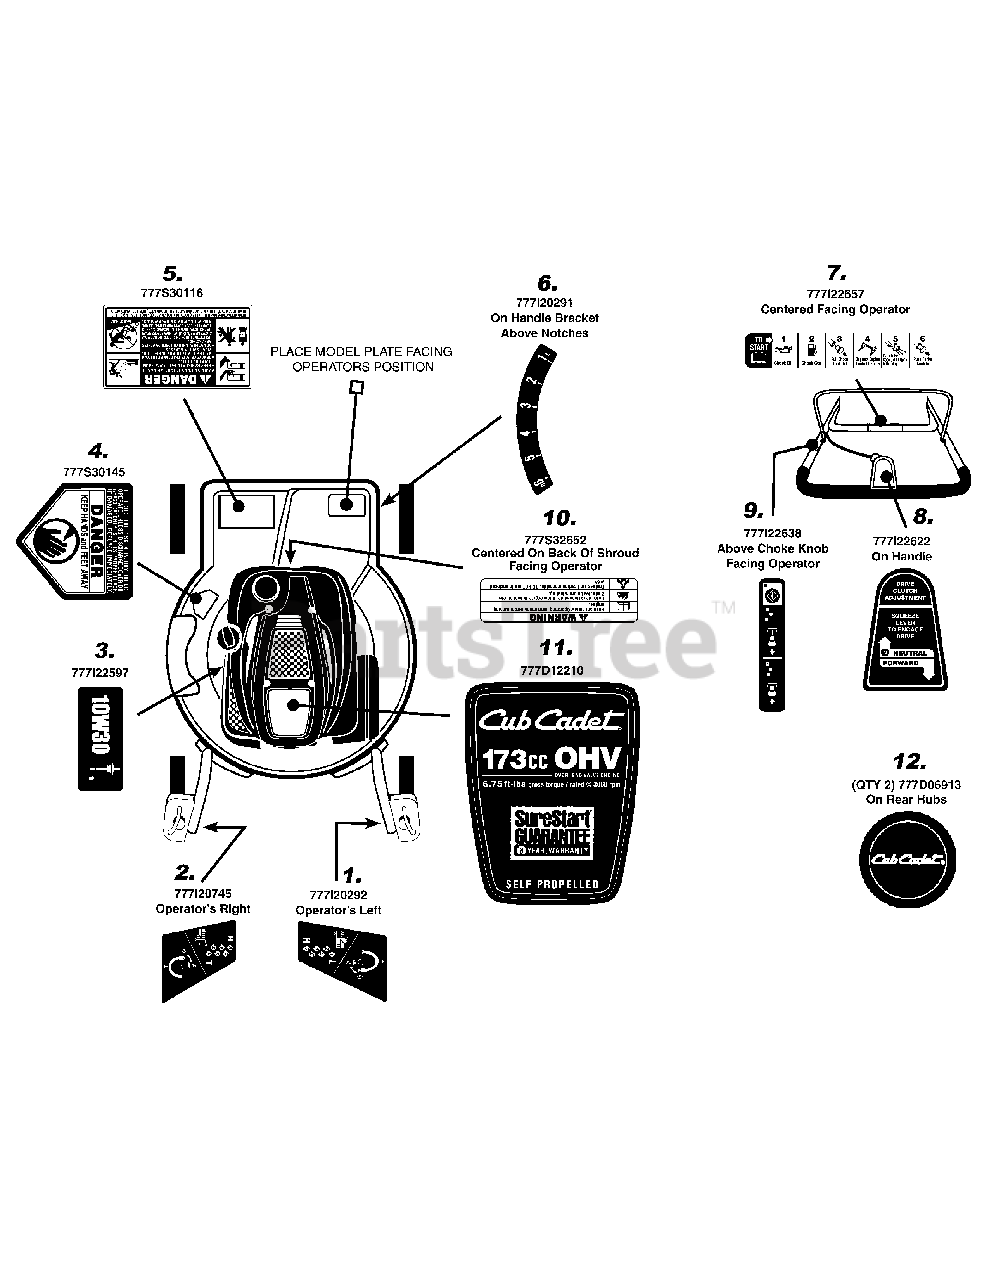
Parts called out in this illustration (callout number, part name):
1	LABEL-CASTOR LOCK
2	LABEL-CASTOR LOCK
3	LABEL:MOWER SHROUD
4	LABEL
5	LABEL-MOWER DANGER
6	LABEL-HEIGHT ADJUS
7	LABEL-MOWER HANDLE
8	LABEL-REAR WHEEL CONTROL LEVER
9	LABEL-MOWER HANDLE:CHOKE START/RUN
10	LABEL:MOWER:ENGINE SHROUD
11	LABEL-173CC SHROUD OHV SELF PROPEL
12	LABEL-HUB CAP
